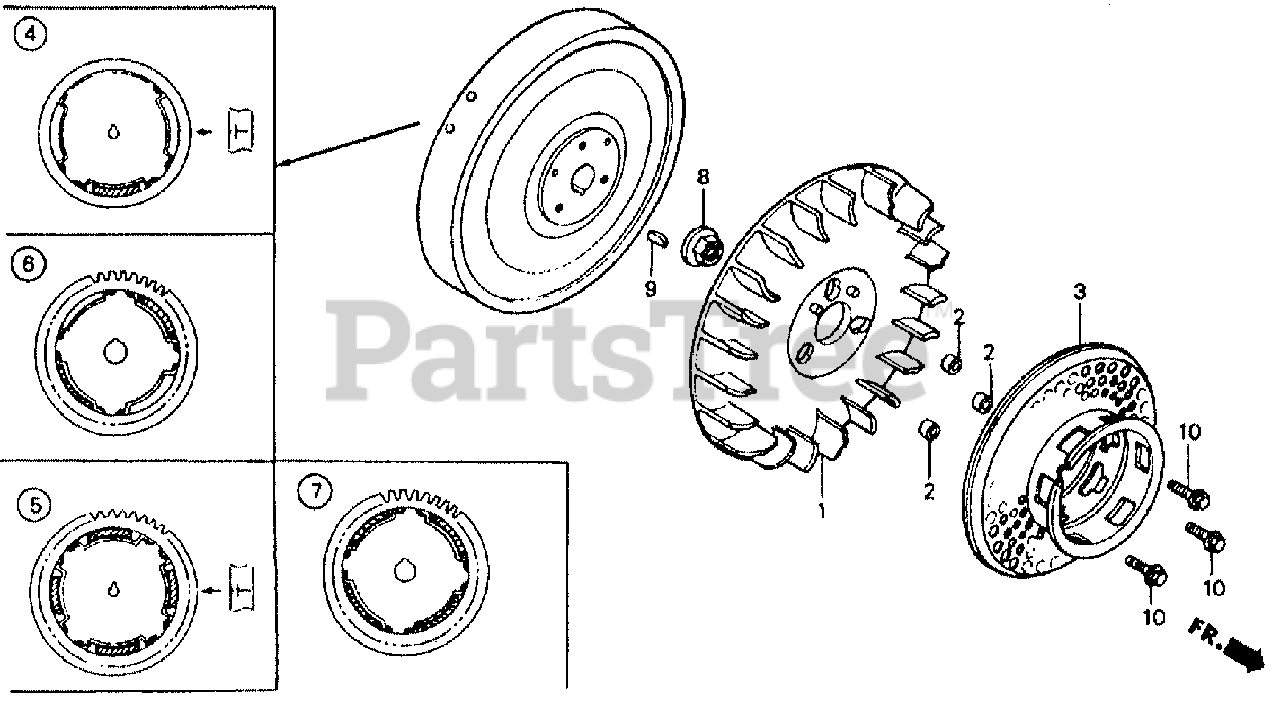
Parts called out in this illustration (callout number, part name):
1	FAN, COOLING
2	COLLAR, FAN
3	PULLEY, STARTER
4	FLYWHEEL (C.D.I.)
5	FLYWHEEL (BREAKER+STARTER)
6	FLYWHEEL
7	FLYWHEEL (STARTER+RECTIFIER)
8	NUT, SPECIAL (16MM)
9	KEY, SPECIAL WOODRUFF (25X18)
10	BOLT, FLANGE (6X16)
